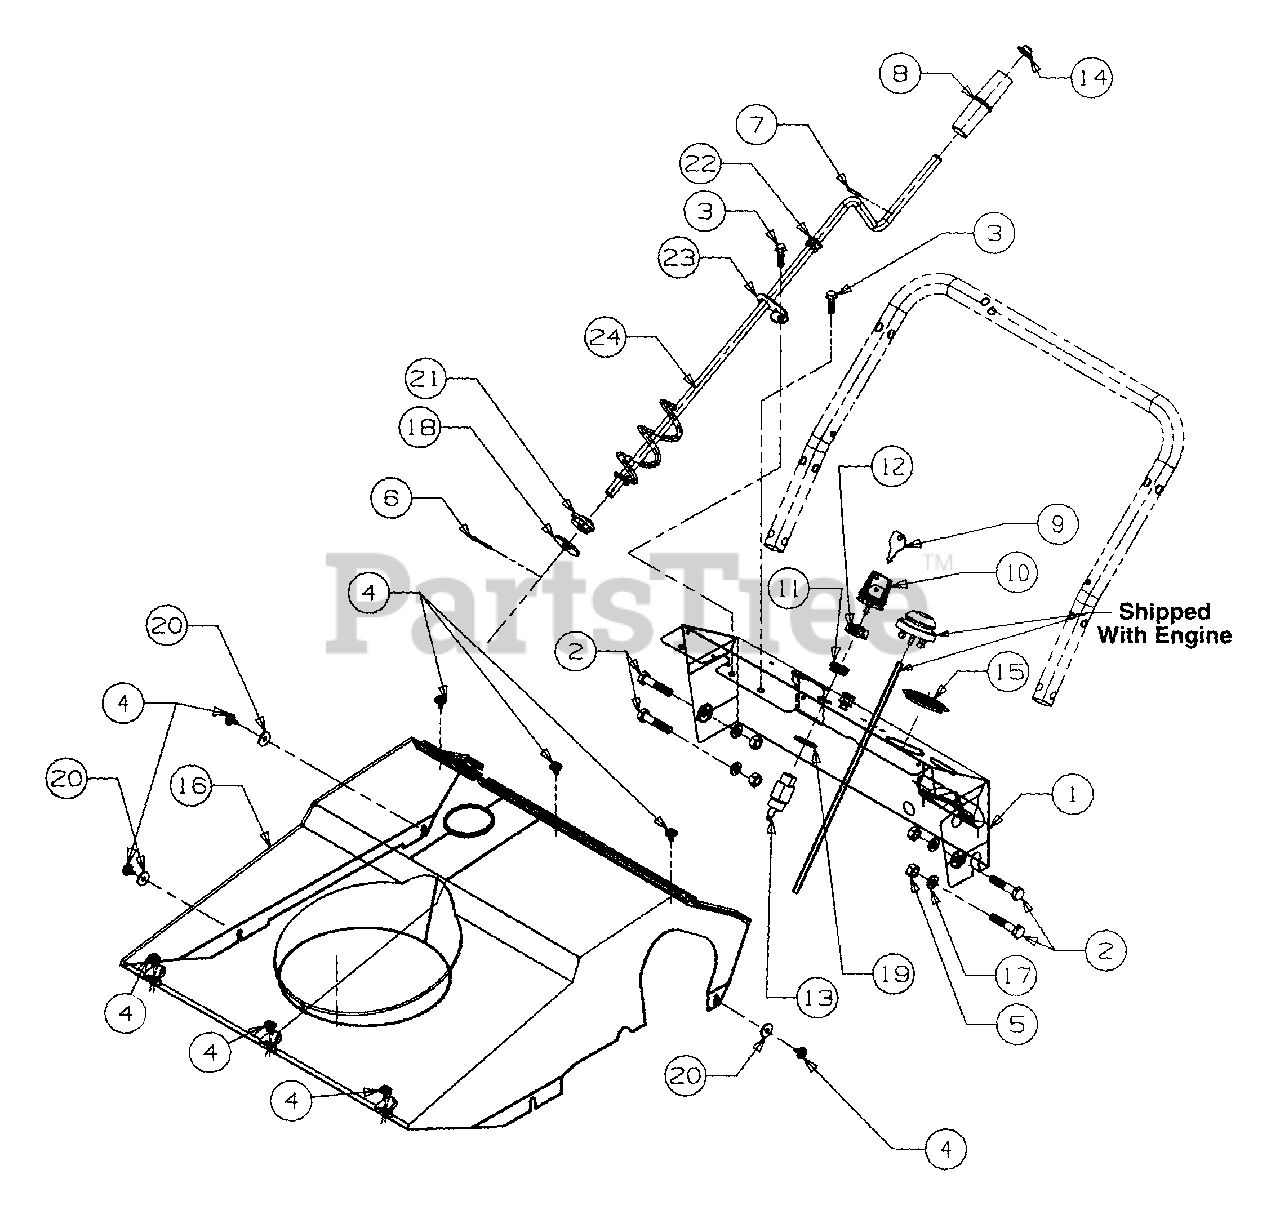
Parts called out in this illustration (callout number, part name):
3	Screw - Hex
4	Screw - Hex
5	Nut - Hex
6	Pin - Cotter
7	Pin - Roll
8	Knob - Chute Crank
9	Key - Ignition
10	Key - Ignition with Logo
11	Nut - Ignition Switch
12	Cap - Ignition Switch
13	Switch
14	Gap - Push
15	Plug - Snap In
16	Shroud - Gray
17	Washer - Lock
18	Washer - Flat
19	Washer - Lock Internal
20	Washer - Flat
21	Bushing - Hex
22	Bushing - Plastic
23	Bracket - Upper Chute Crank
24	Crank - Chute
